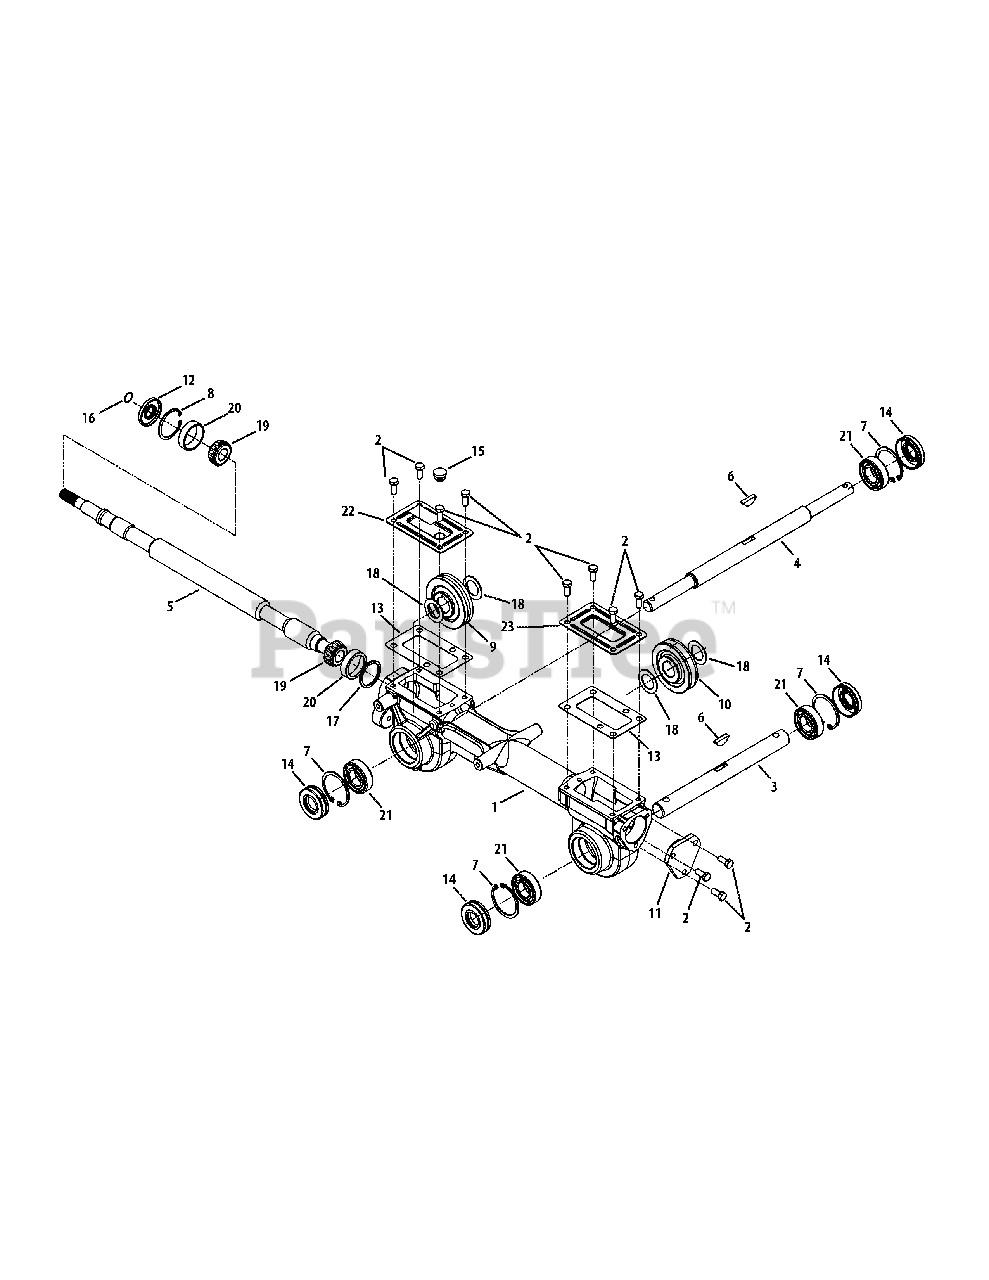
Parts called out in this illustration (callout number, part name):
1	Housing, Transmission
2	Hex Screw, 5/16-18, .75, Gr5
3	Shaft, Tiller
4	Shaft, Wheel
5	Shaft, Worm
6	Key, Hi Pro .25 x 1.062
7	Retaining Ring
8	Retaining Ring, Int
9	Worm Gear, 61t, RH
10	Worm Gear, 30t, LH
11	Bearing Cover
12	Seal, Oil, .750 Shaft x 1.783 Bore
13	Gasket, Gear Housing
14	Seal, Oil, 1.00 Shaft x 2.00 Bore
15	Rubber Plug, Oil
16	Wire Ring
17	Washer, Flat, 1.50 x 1.75 x .062
17	Washer, Flat, 1.50 x 1.75 x .005
17	Washer, Flat, 1.50 x 1.75 x .03
17	Washer, Flat, 1.50 x 1.75 x .010
18	Washer, Flat, 1.010 x 1.56 x .060
19	Cone Bearing
20	Bearing Cup
21	Ball Bearing
22	Cover, Transmission
23	Cover, Transmission
